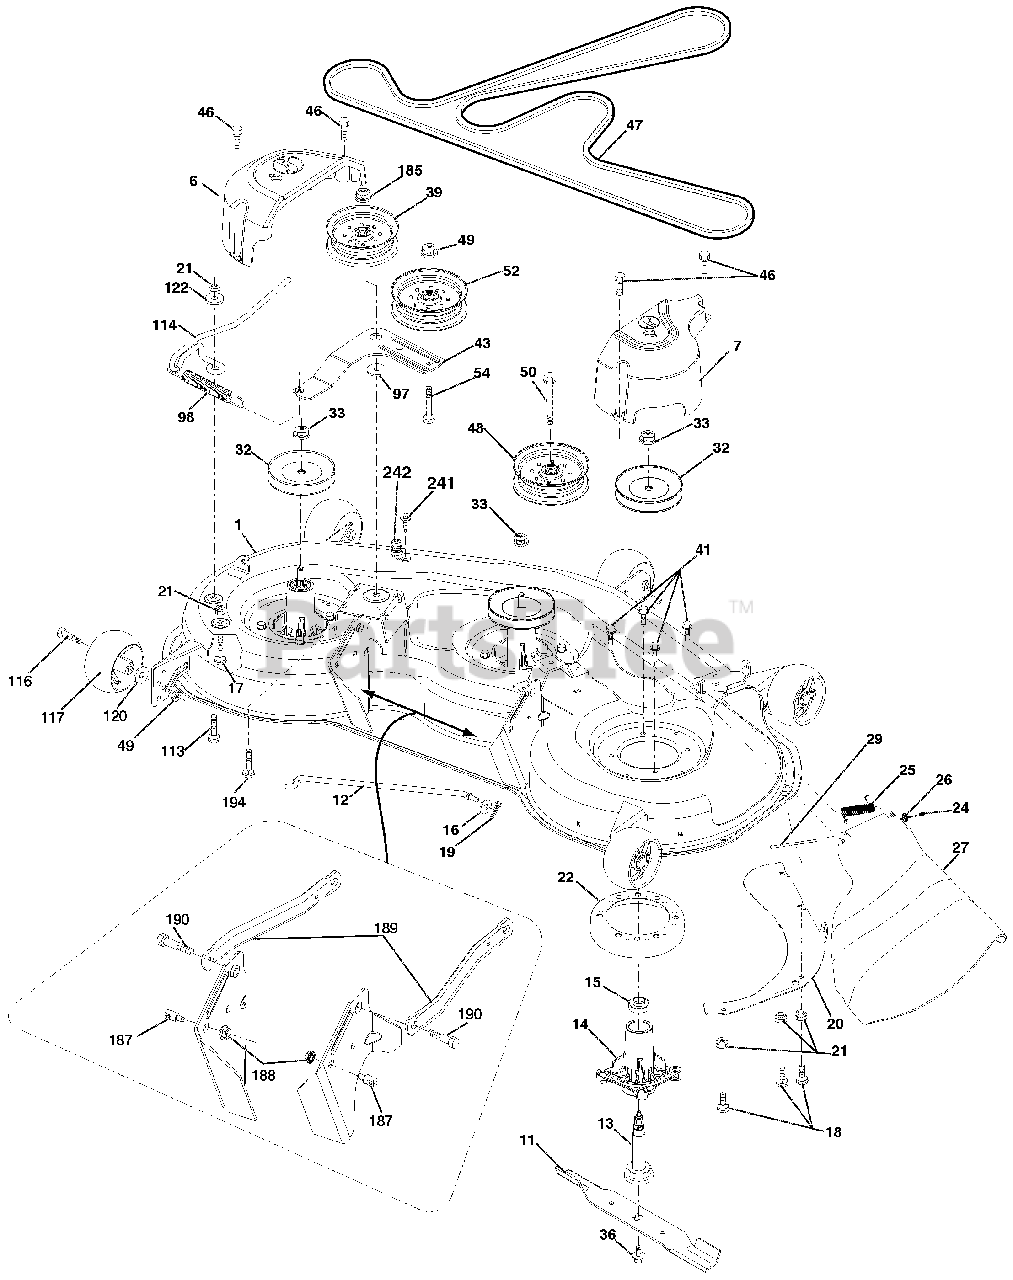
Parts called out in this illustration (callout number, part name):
6	COVER MANDREL LH
7	COVER MANDREL RH
11	48" BAGGER BLADE
11	BLADE, MULCH 42" 16.75"
12	ROD.ANTI SWAY.48/54"K46.TEX
13	SHAFT ASSEMBLY
14	HOUSING.MANDREL.4PT.SERVICE
15	BEARING
16	Washer 13/32 x 13/16 x 12 Ga.
17	BOLT.CARR.5/16-18 X 5/8 SHORT
18	BOLT.RDHD.SQNK.5/16-18 X 5/8
19	PIN.COTTER.5/16.BOW TIE LOCK
20	BAFFEL VORTEX
21	Nut, Hex, Crownlock 5/16-18
22	STRIPPER.MANDREL.DECK
24	CAP.SLEEVE..80X.112.BLK.MOWER
25	SPRING.TORSION.48"
26	NUT.PUSH.PHOS.& OIL
27	DEFLECTOR SHIELD
29	ROD.HINGE.42/46"
32	PULLY, MANDREL
32	MANDREL ASSEMBLY
33	NUT.FLANGE.LOCK.TOP
36	SCREW 7/16-20 X 1
39	PULLEY.IDLER.4.50.HUB.SPECIAL
41	HEX HEAD BOLT
43	ARM.ILDER
46	SCREW.THD.ROLL.1/4-20 X 5/8
47	PRIMARY MOWER BELT 48"
48	PULLEY.IDLER.4.50.RAW
49	Nut, Hex, Flangelock 3/8-16
52	PULLEY.IDLER 48"PRIMARY
54	BOLT.CARR.SH.3/8-16X1-1/2.GR5
97	WASHER.FLAT.HARDENED
98	SPRING.DRIVE.DECK.2006
113	BOLT.CARR.5/16-18UNC X 1
114	ROD TENSION RELIEF
116	BOLT.SHOULDER.3/8-16X3-5/8.GR5
117	WHEEL.GAUGE.RALLY.
120	WASHER.13/32 X 1-1/4 X 12 GA.
122	BUSHING.RELIEF.TENSION
185	NUT.LOCK.FLANGE.7/16-14.GR5
187	STUD.FASTNER.W/'D'ANTI-ROTATIO
188	Nut, Lock Hex Flange 5/16-18 u
189	ARM.SUSPENSION.MOWER.REAR
190	BOLT.SHOULDER
194	BOLT CARR SQNK 3/8-16 X 2-1/4
242	PORT WASHOUT
